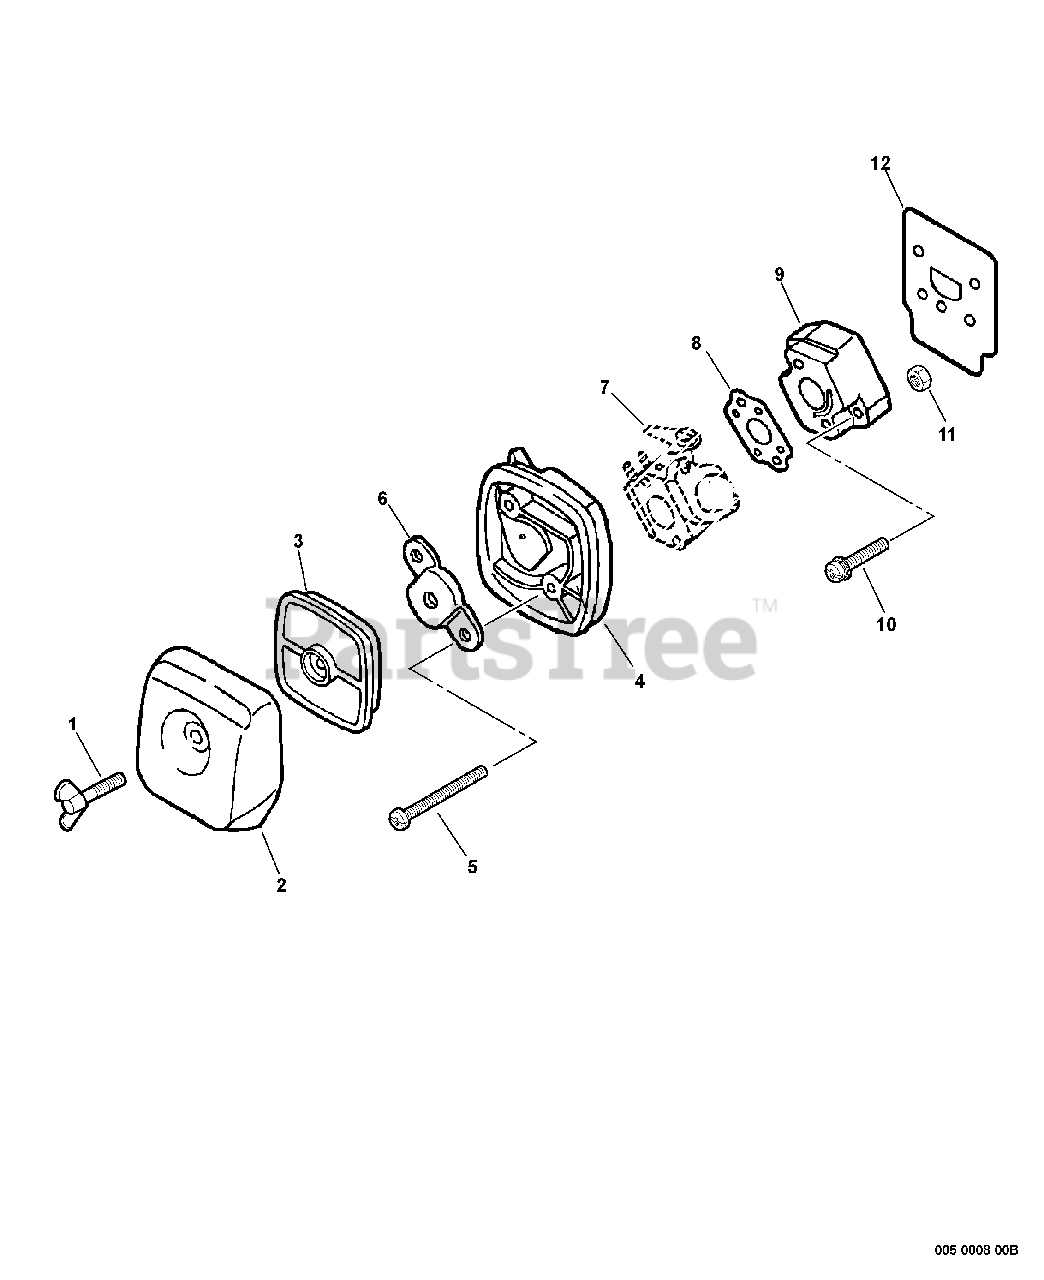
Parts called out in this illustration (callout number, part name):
1	BOLT, WING 5×20
2	COVER, AIR FILTER - GRAY
3	FILTER, AIR - SINGLE LAYER
4	CASE, AIR FILTER - GRAY
5	SCREW 5×65
6	PLATE, PREVENT
7	CARBURETOR
8	GASKET, INTAKE
9	INSULATOR, INTAKE
10	SCREW 5×20
11	NUT M5
12	HEAT SHIELD, INTAKE
